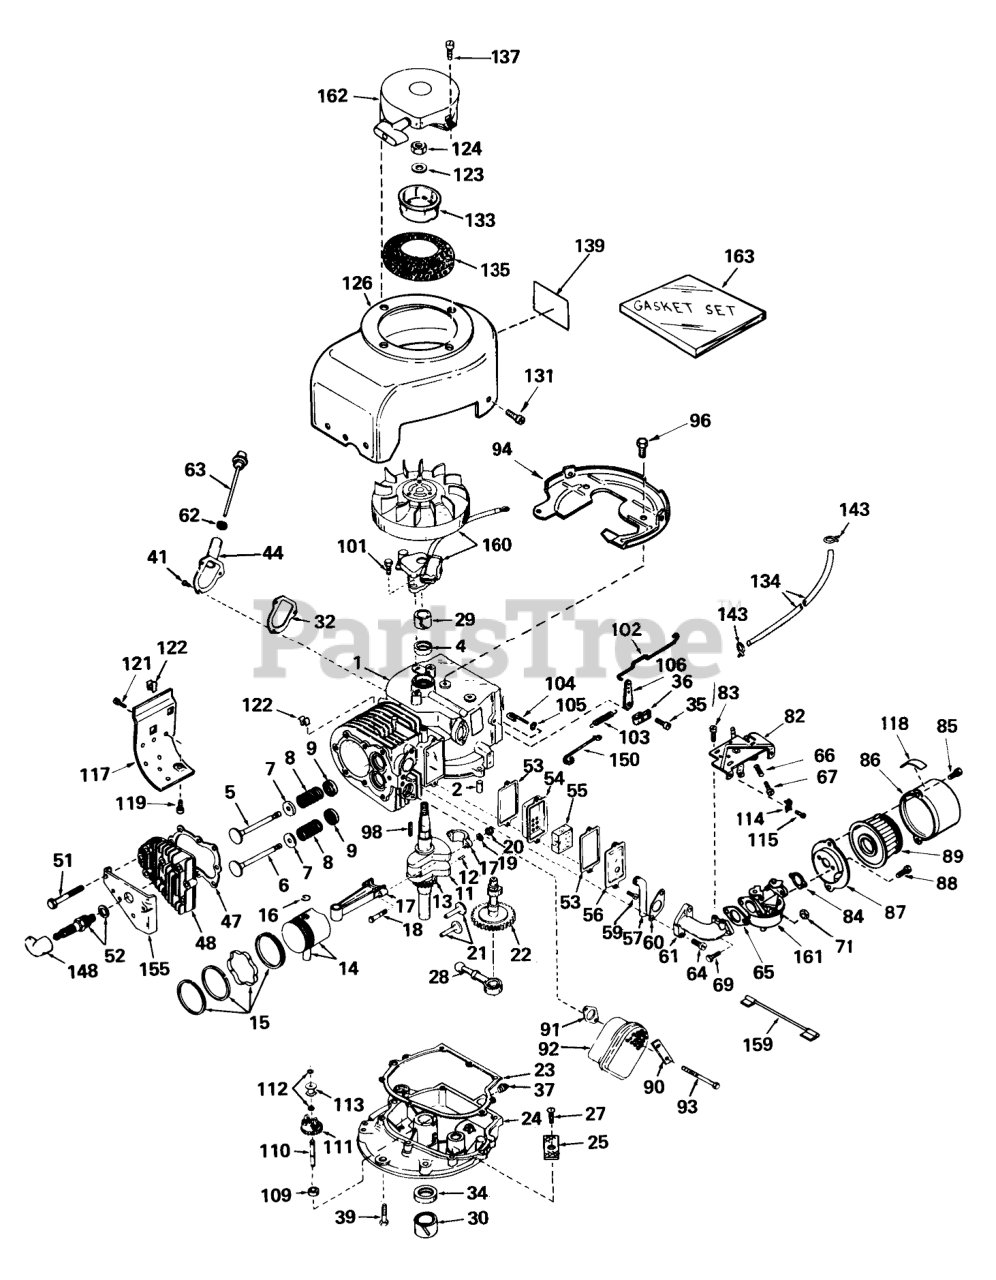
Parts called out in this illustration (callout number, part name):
1	Cylinder Assy. (Incl. Nos. 2, 4, 29, 32 & 41)
2	Pin-Dowel
4	Seal, Oil
5	Valve, Intake (Standard) (Incl. No. 9)
5	Valve, Intake (1/32" oversize) (Incl. No. 9)
6	Valve, Exhaust (Standard) (Incl. No. 9)
6	Valve, Exhause (1 /32" oversize) (Incl. No. 9)
7	Cap-Spring, Valve
8	Spring-Valve
9	Keeper-Spring, Valve
11	Crankshaft Assy. (Incl. Nos.12 & 13)
12	Pin, Groove
13	Gear-Crankshaft
14	Piston & Pin Assy. (Incl. 2 of No. 16) (Standard)
14	Piston & Pin Assy. (.010 over-size) (Incl. 2 of No.16)
14	Piston & Pin Assy. (.020 over-size) (Incl. 2 of No. 16)
15	Ring Set, Piston (Standard)
15	Bearing-Wrist Pin
15	Bearing-Crankshaft
16	Ring-Retaining, Piston Pin
17	Rod Assy., Connecting (Incl. Nos. 18, 19 & 20)
18	Bolt, Connecting Rod
21	Lifter Valve
22	Camshaft (Compression Release)
23	Gasket-Cover, Cylinder
24	Flange Assy., Mounting (Incl. Nos. 25, 27, 30, 37, 62 & 110)
25	Screen-Oil Filter
28	Pump, Oil
29	Bushing, Crankshaft
30	Bushing, Crankshaft
32	Gasket, Filler tube
34	Seal-Oil
35	Screw
36	Clamp-Lever, Governor
37	Plug-Drain, Oil (SQH 1/4-18)
39	Screw (1/4-20 x 1-1/4)
44	Tube, Oil Filler
47	Gasket-Head, Cylinder
48	CYLINDER HEAD
51	Screw Hex Hd. Cap
52	Plug, Spark (J17LM or equiv.)
53	Gasket-Breather
54	Body-Breather
55	Element-Breather
56	Cover-Valve
57	Tube-Breather
60	Gasket-Intake
61	Pipe, Intake
62	Gasket
63	Dipstick, Oil (Incl. No. 62)
64	Screw (T-30, 5/16-18x1-3/32)
65	Gasket
66	Spring-Compression
67	Screw
69	Screw (1/4-28 x 7/8)
71	Nut and Lock Washer (1/4-28)
82	Control Assy., Speed (Incl. Nos. 66 & 67)
83	Screw (10-24 x 9/16)
84	Gasket
86	Body
87	Bracket
88	Screw (10-32 x 1/2)
89	Element
90	Plate-Locking
91	Gasket Exhaust
92	Muffler
93	Screw Hex Hd.
94	Baffle Blower Housing
96	Screw (1/4-20x19/32)
98	Key, Flywheel
102	Link Governor
103	Spring Governor
104	Rod, Governor (Incl. No.105)
105	Washer-Flat
106	Lever-Governor
109	Spacer
110	Shaft, Governor
111	Governor Gear ASM
112	Ring-Retaining
113	Spool-Governor
114	Conduit
115	Screw (10-32 x 3/8)
117	Emnsion, Blower Housing
121	Screw
122	51004 GIL ROTARY TI
123	Washer
126	Housing, Blower
131	Screw, Hex Hd.
133	Cup-Starter
134	Line-Fuel
135	Screen, Air
139	480B GIL SNWTHWR O/
143	Clamp-Line, Fuel
148	Cover-Spark Plug
150	Link Governor Spring
155	Cover-Head, Cylinder
159	Wire, Ground
161	Carburetor
162	Starter, Rewind
163	Gasket Set
